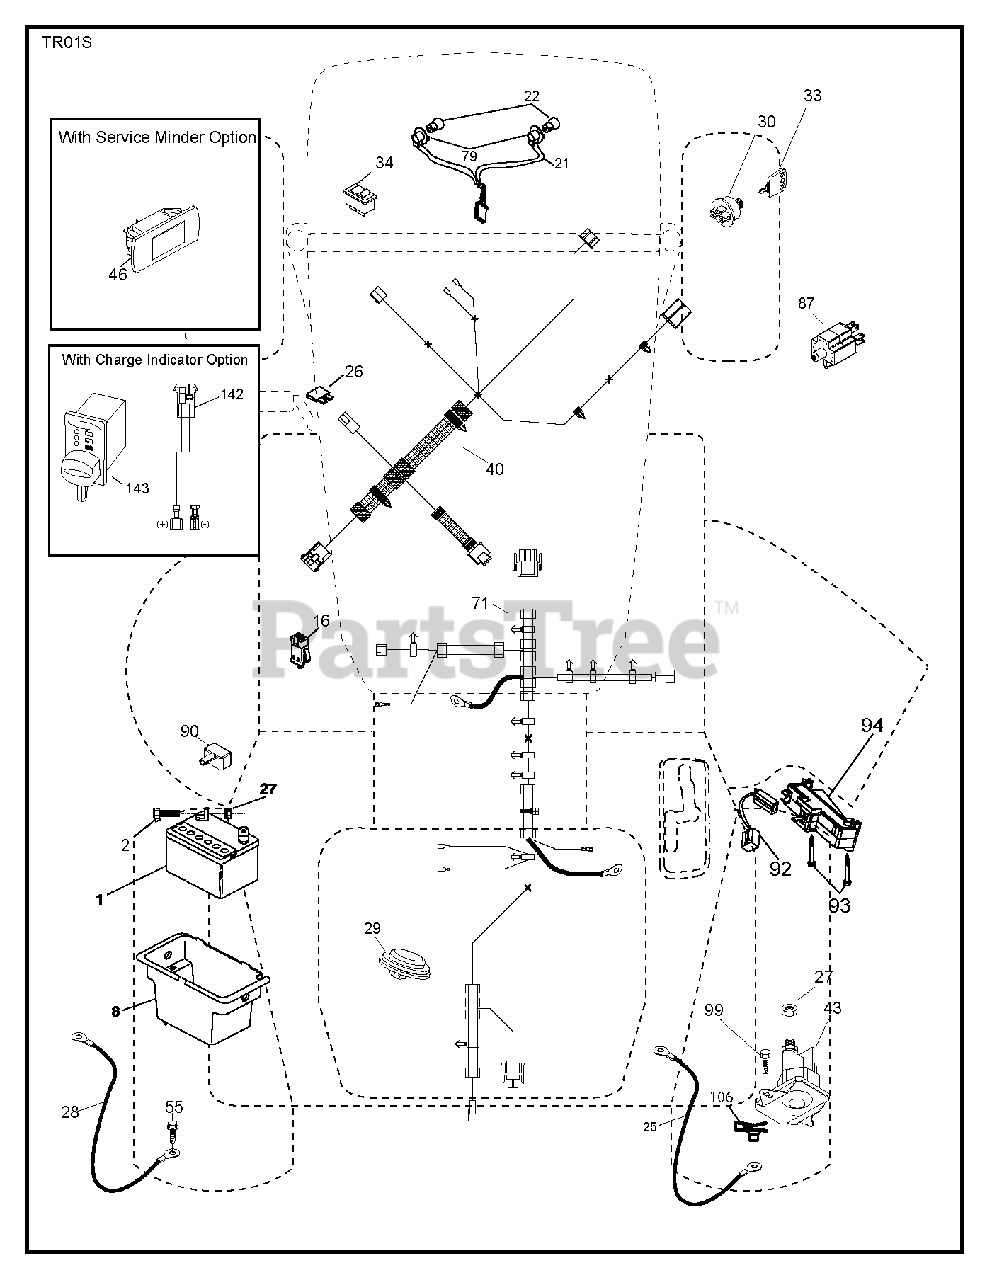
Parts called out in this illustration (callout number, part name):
1	Battery, Dry 30 Amp
2	BOLT.HEX.1/4.X.3/4.DICHROMATE
8	BOX.BATTERY.MNT.REAR.L
16	SWITCH INTERLOOK PUSH-IN
21	HARNESS.LIGHT W/4152J BULBS
25	CABLE.BATT.RED.8GA.17
26	FUSE 20AMP
27	NUT
28	CABLE.GROUND.REAR.BATTERY.8G
29	SWITCH.SEAT.DELTA.OPC.
30	SWITCH.IGN.DELTA.W.LGH.ROS
33	KEY.CHAIN.BLISTER.PACK.GEN.INT
40	HARNESS.DASH.RRBATT.CC.CHG
43	SOLENOID.W/BRASS.PLUNGER
55	SCREW 5/16"
71	HARNESS.CHASSIS.RRBATT.RDYSTRT
79	BULB HOLDER ASM.
87	SWITCH.INTRLCK.CLUTCH.
90	COVER.TERMINAL.BATTERY
92	HARNESS.PIGTAIL.CONSLE
93	SCREW.PLASTITE
94	MODULE.REVERSE.ROS
99	SCREW HEXWSHR 1/4-20X3/4
106	1/4-20 U NUT
142	CHARGE.PORT.PIGTAIL HARNESS
143	CHARGE.PORT
